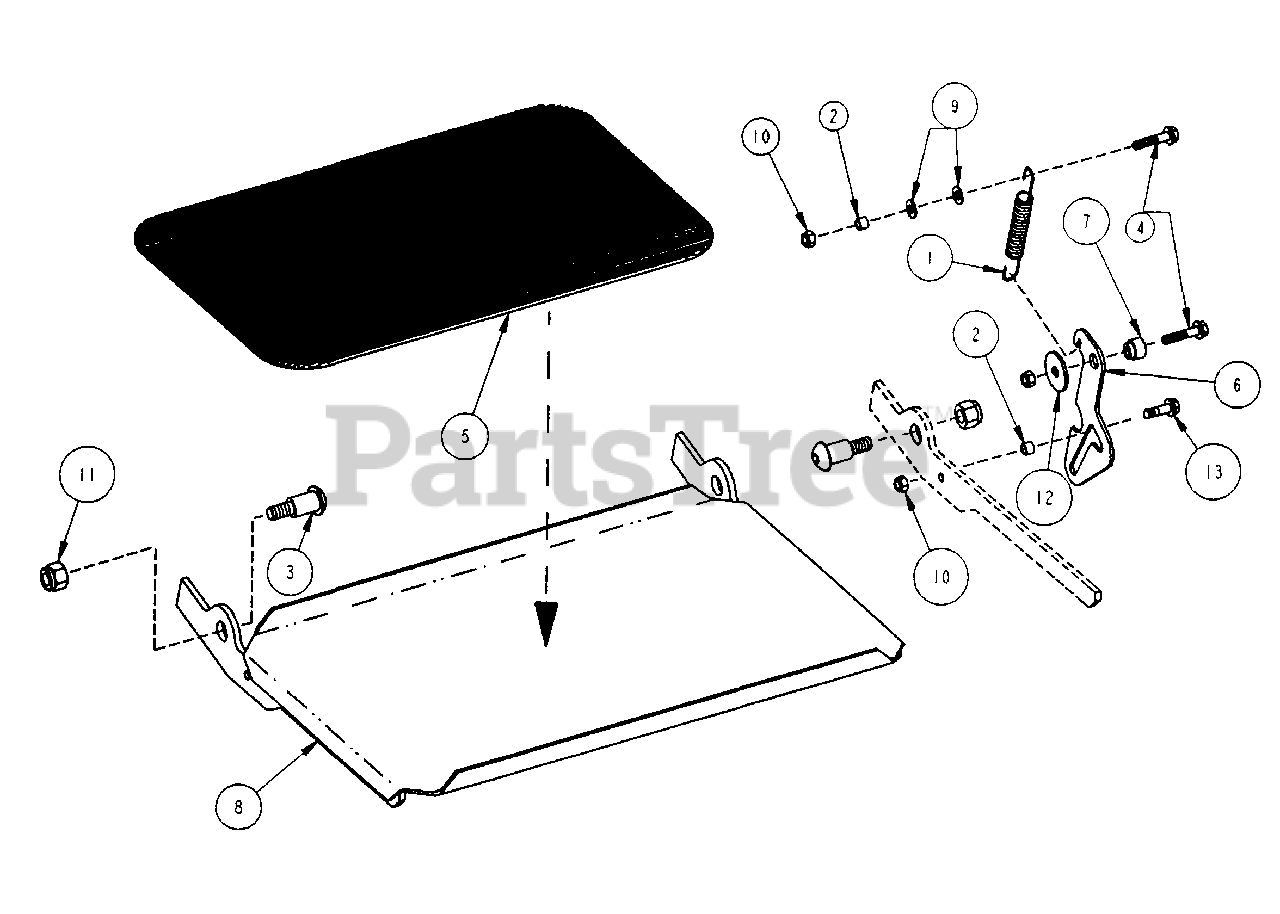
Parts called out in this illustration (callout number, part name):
2	BUSHING, 5/16 I.D x 7/16 O.D. x 3/16
3	BOLT, 1/2-13, 3/4 Dia. X 1-1/16 Shoulder
4	BOLT, 5/16-18 x 1-1/2 Hex Flange Lock, Grade 5
5	FOOT PAD, Rubber
6	PLATE, Footrest Latch
7	SPACER, Shoulder (Latch)
8	FOOTREST (Weldment)
9	WASHER, 11/32 I.D. x 11/16 O.D. x 1/16" Flat
10	NUT, 5/16-18 HEX NYLON LOCK
11	NUT, 1/2-13 Nyloc
12	WASHER, 13/32 I.D. x 1-1/2 O.D. x 1/8" Flat
13	BOLT, 5/16-18 x 1 Hex Flange Lock, Grade 5
